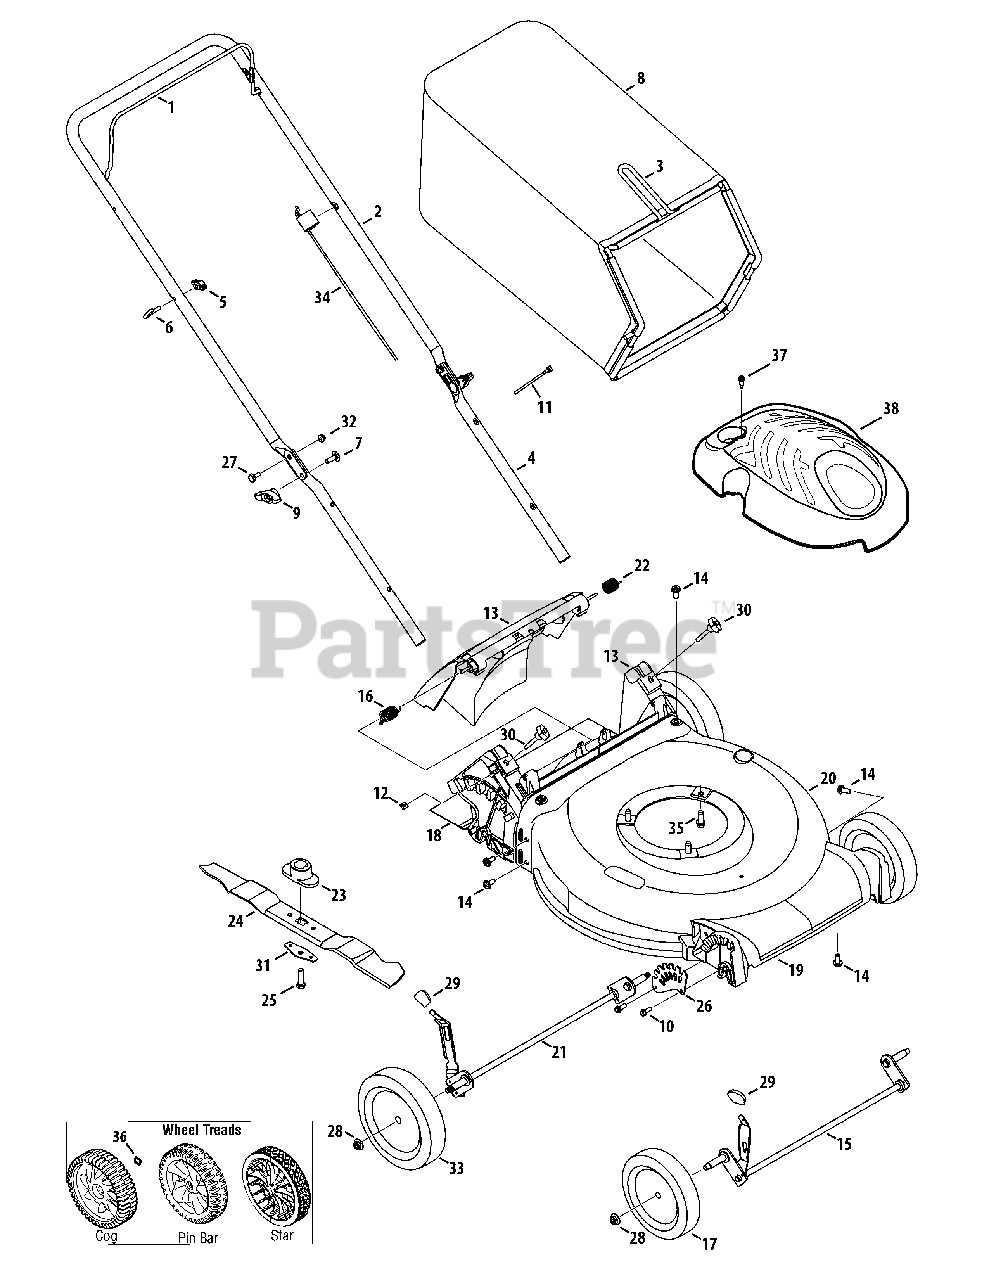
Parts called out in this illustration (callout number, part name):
1	Blade Control
2	Upper Handle
4	Lower Handle
5	Wing Nut
6	Rope Guide
7	Carriage Screw ,5/16-18
8	Grass Bag
9	Wing Knob
10	Screw, 1/4-15 x .750
11	Cable Tie
12	Nut, Sq., 1/4-20
13	Rear Door Assembly
14	Screw, 5/16-14 x .750
15	Front Axle Assembly
16	Torsion Spring - RH
17	Front Wheel, 7 x 1.8, Bar, Gray
18	Trail Shield
19	Front Cover
20	Deck - 21"
21	Rear Axle Assembly
22	Torsion Spring - LH
23	Blade Adapter
24	Mulching Blade
25	Screw , 3/8-24 x 1.50
26	Front Height Adjuster Plate
27	Sldr. Screw, .375 x .126 x 1/4-20
28	Flange Lock Nut, 3/8-16
29	Adjustment Lever Knob
30	Wing Nut
31	Blade Bell Support
32	Nut, Flange Lock, 1/4-20
33	Rear Wheel, 8 x 1.8, Bar, Gray
34	Control Cable, 48"
35	TT Sems Screw, 3/8-16 x 1.0
36	Wave Washer, .510 x .750 x .017
37	Screw, HL, #12-16 x 1.00
38	Engine Shroud M1.1 Black
